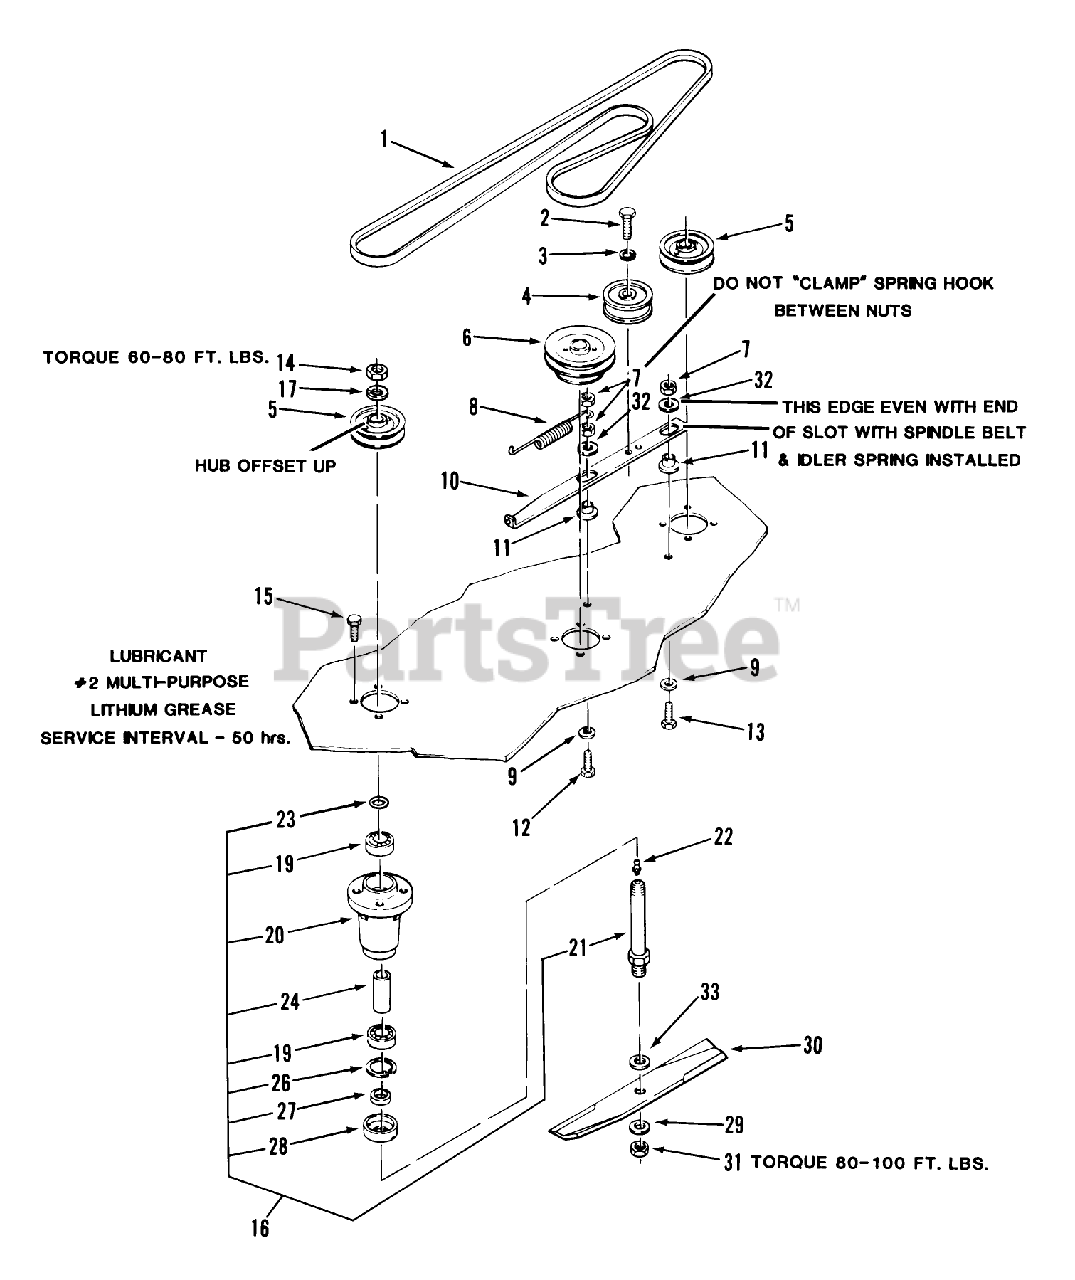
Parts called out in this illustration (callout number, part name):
1	V-BELT
1	V BELT
2	Bolt
2	BOLT HEX SPECIAL
3	LOCKWASHER
4	Idler Pulley
5	PULLEY-BLADE, DRIVE
5	PULLEY
6	PULLEY-MOWER, 48IN
6	PULLEY
7	NUT
8	SPRING-EXTENSION
9	WASHER
10	BAR-IDLER SUPPORT
11	SPACER-BUSHING
12	Bolt
13	Bolt
14	Jam Nut
15	Bolt
16	Spindle Assembly
17	Lockwasher
19	BEARING-BALL
20	HOUSING-SPINDLE
21	Spindle Shaft
22	Zerk
23	O RING
26	Ring-Snap
27	SPACER-BLADE
28	CUP-SPINDLE
29	Washer
29	SpeciaI Washer
30	BLADE KIT (3 PACK)
30	14IN BLADE KIT
30	BLADE KIT
31	Nut-Jam
32	WASHER
33	SpeciaI Washer
33	Washer
